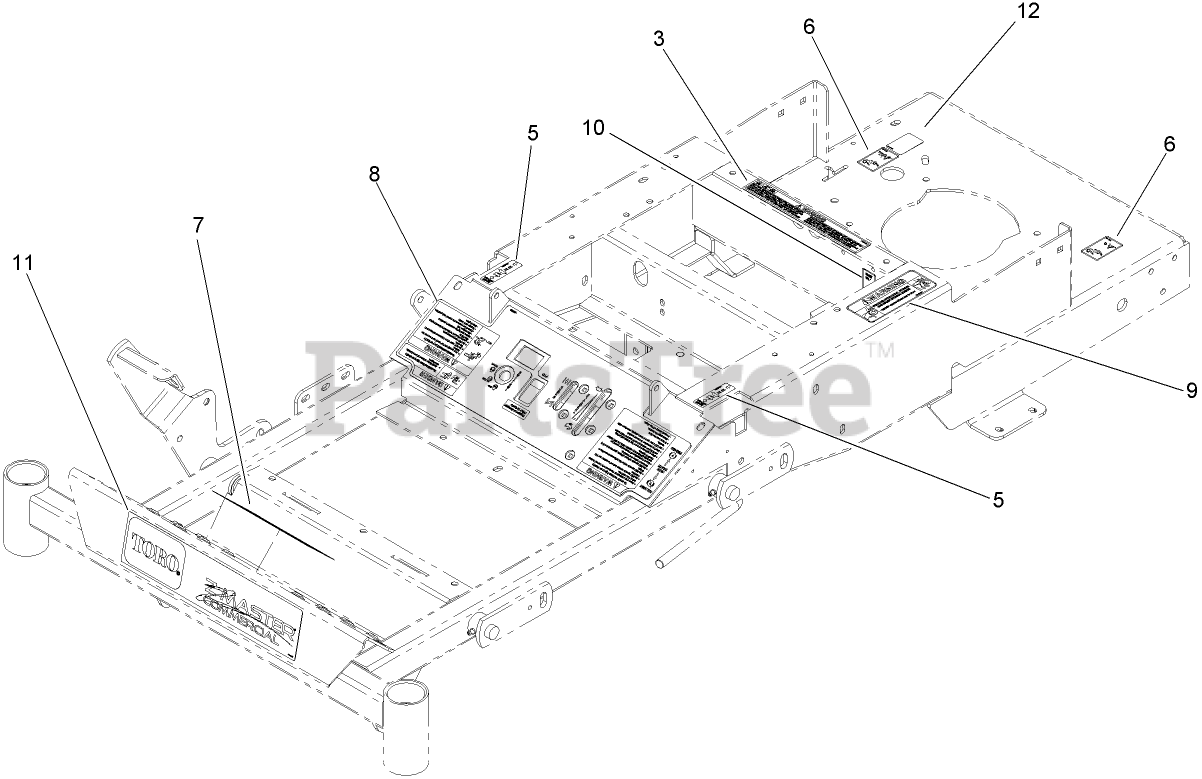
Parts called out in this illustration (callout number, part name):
3	DECAL-BATTERY
5	DECAL-CONTROL, MOTION
6	DECAL-TRANSPORT, CE
7	DECAL-SLOPE, DANGER
8	DECAL-CONSOLE
9	DECAL-DEVICES, ROTATING
10	DECAL-RELAY
12	DECAL-SURFACE, HOT
